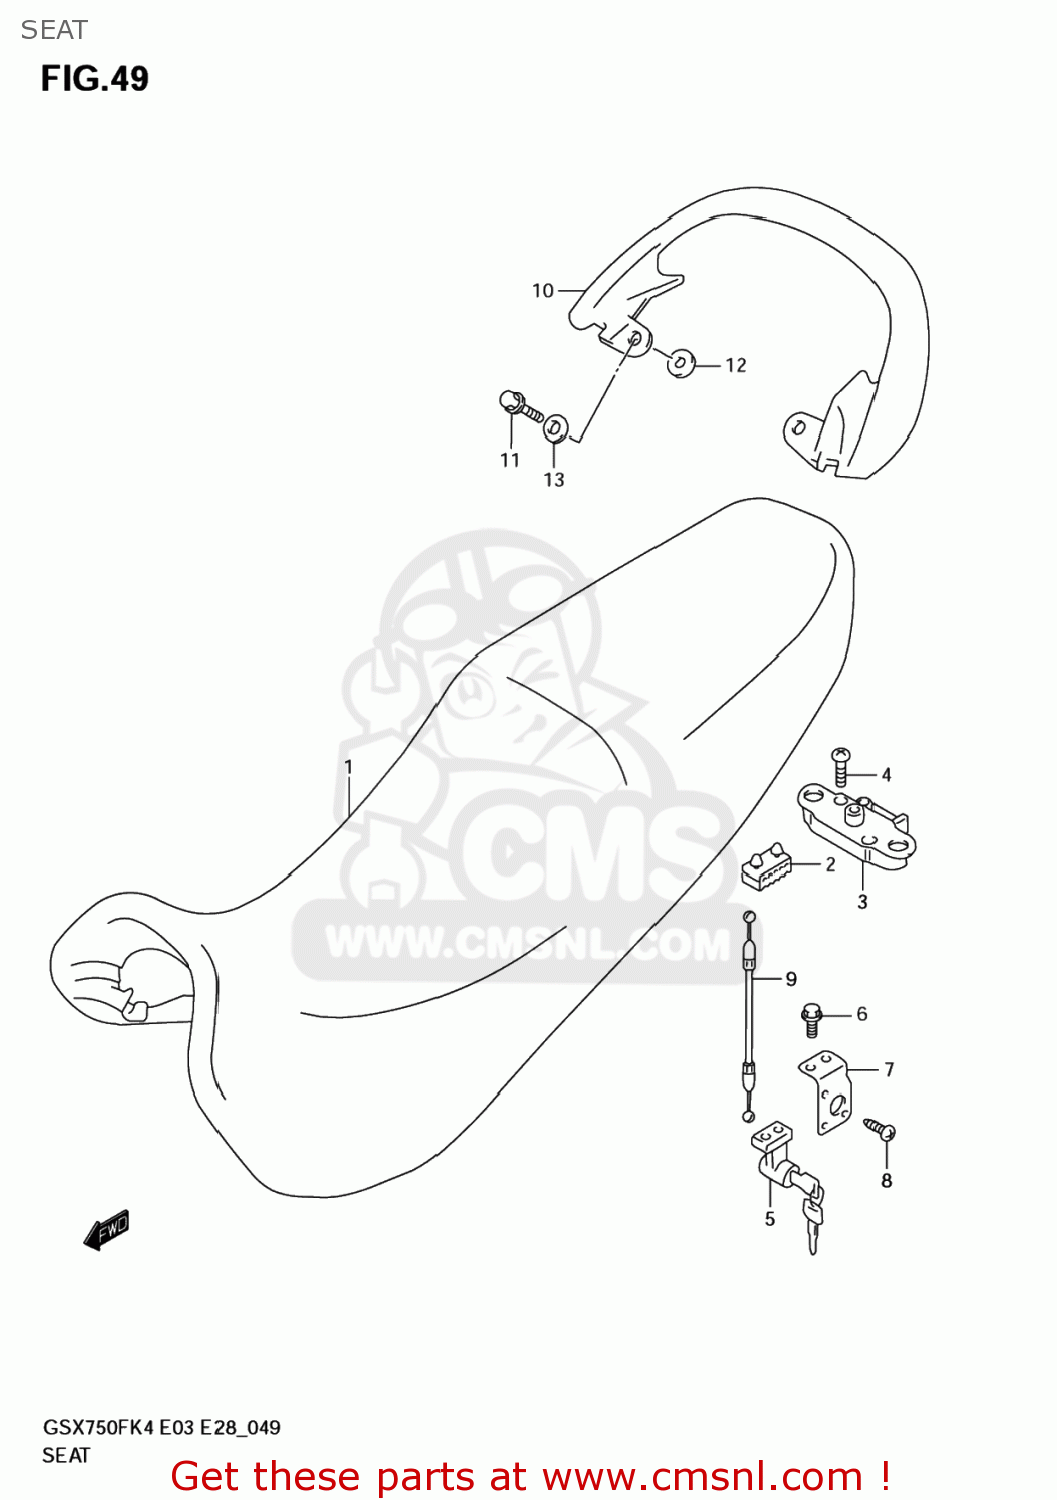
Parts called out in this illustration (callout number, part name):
1	SEAT ASSY
2	CUSHION
3	BRACKET,SEAT SUPPORT,RIGHT
4	SCREW
5	LOCK SET,SEAT
6	BOLT
7	BRACKET,SEAT LOCK
8	SCREW
9	CABLE,SEAT LOCK
10	HANDLE,PILLION RIDER
11	BOLT.MUF SPRT F
12	CUSHION,RIDER HNDL(17X24X1.5)
13	WASHER(8.5X24X2.3)
